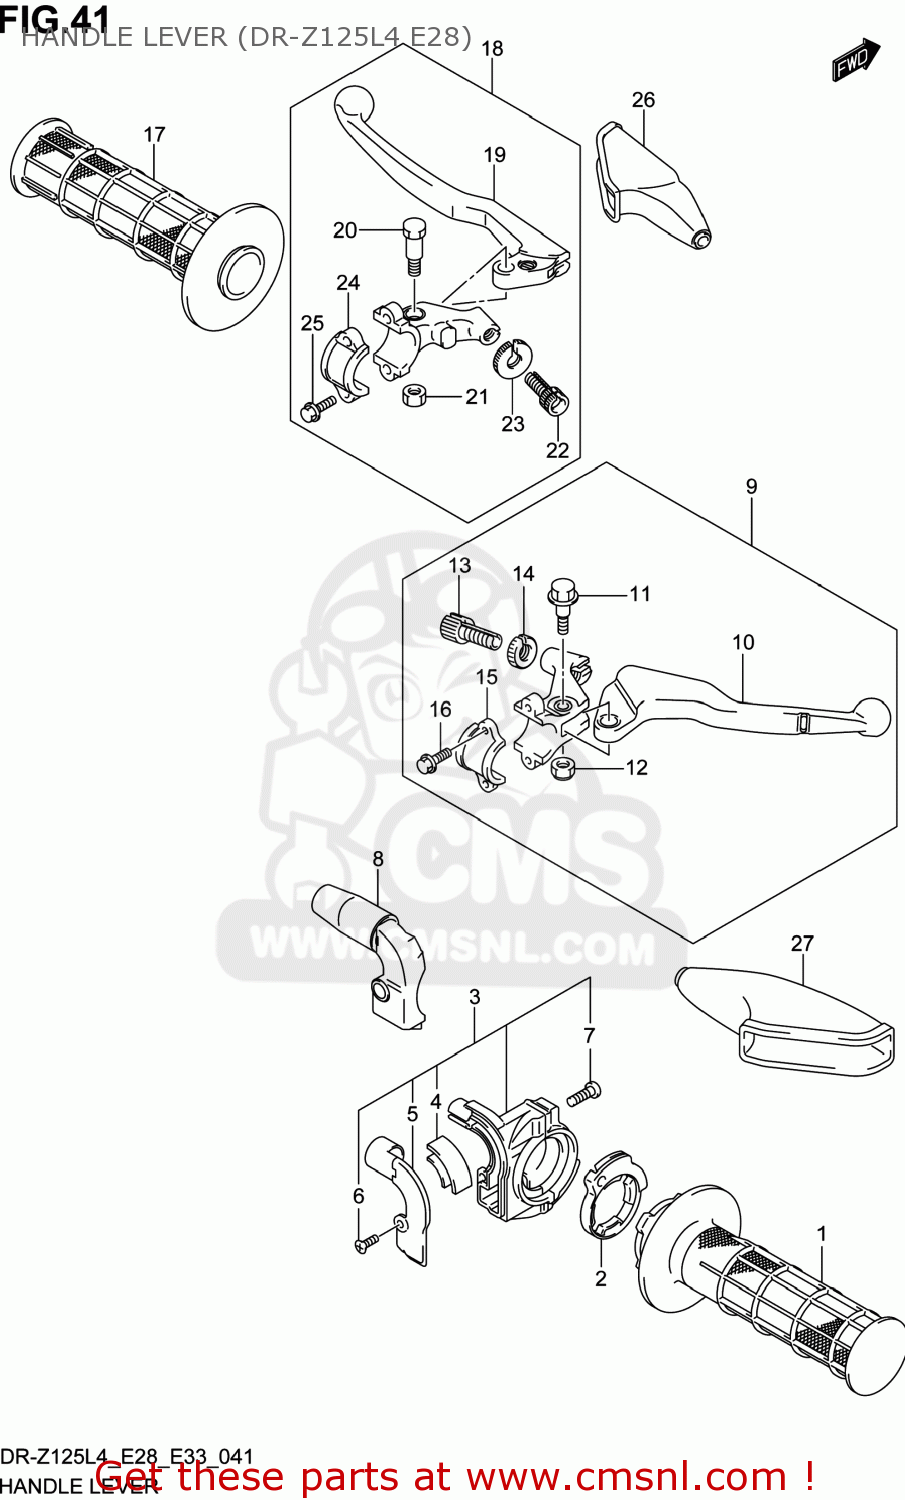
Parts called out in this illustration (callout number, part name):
1	GRIP,THROTTLE
2	ROTER,THROTTLE
3	CASE ASSY,THROTTLE
4	GUIDE
5	COVER
6	SCREW
7	SCREW
8	COVER,THROTTLE CASE
9	LEVER ASSY,BRAKE
10	LEVER,BRAKE
11	BOLT,LEVER PIVOT
12	NUT
13	ADJUSTER,WIRE
14	NUT,LOCK
15	HOLDER
16	BOLT
17	GRIP,L
18	LEVER ASSY,CLUTCH
19	LEVER,CLUTCH
20	BOLT,LEVER PIVOT
21	NUT
22	ADJUSTER,WIRE
23	NUT,LOCK
24	BRACKET,CLUTCH LEVER HOLDER
25	BOLT,BRACKET
26	COVER,CLUTCH CABLE DUST
27	COVER,CLUTCH LEVER
